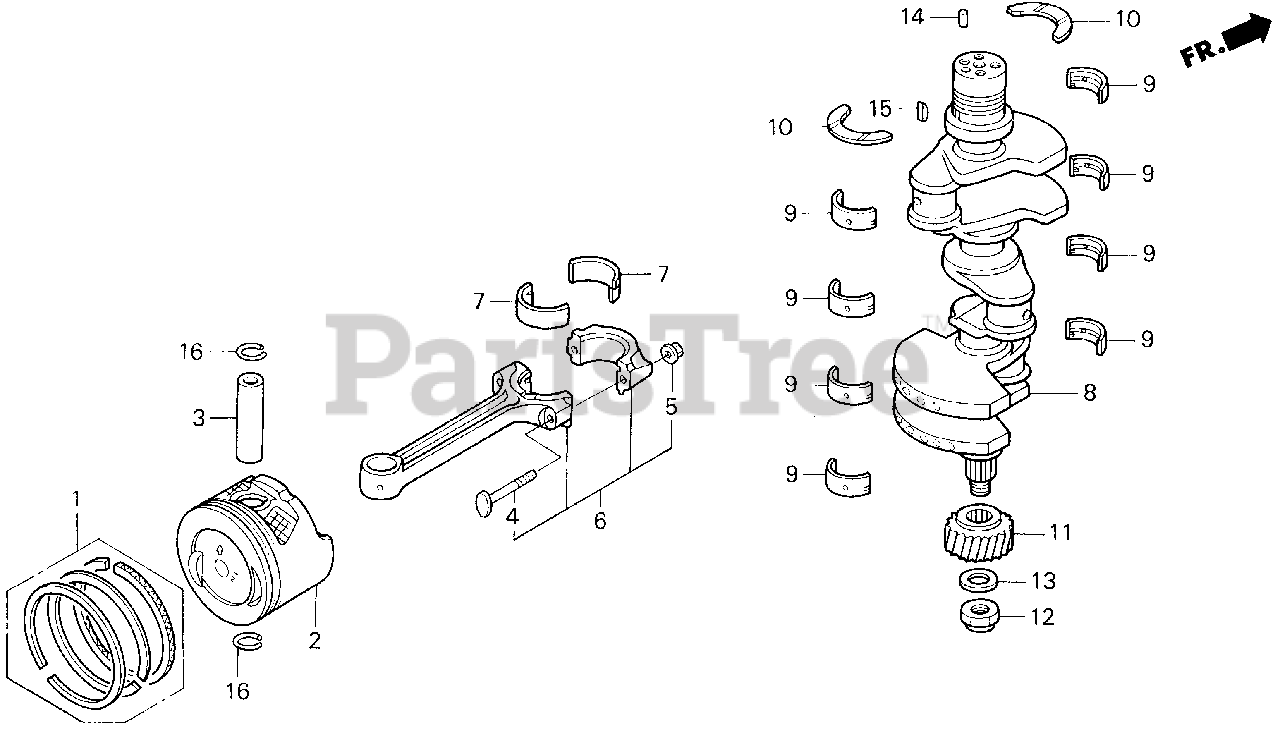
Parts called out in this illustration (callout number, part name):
1	RING SET, PISTON
1	RING SET, PISTON (OS 0.25)
2	PISTON (OS 0.25)
3	PIN, PISTON
4	BOLT, CONNECTING ROD
5	NUT, CONNECTING ROD
6	ROD SET, CONNECTING
7	BEARING A, CONNECTING ROD (BLUE)
7	BEARING B, CONNECTING ROD (BLACK)
7	BEARING C, CONNECTING ROD (BROWN)
7	BEARING D, CONNECTING ROD (GREEN)
7	BEARING E, CONNECTING ROD (YELLOW)
7	BEARING F, CONNECTING ROD (PINK)
7	BEARING G, CONNECTING ROD (RED)
8	CRANKSHAFT
9	BEARING A, MAIN (BLUE) (DAIDO)
9	BEARING B, MAIN (BLACK) (DAIDO)
9	BEARING C, MAIN (BROWN) (DAIDO)
9	BEARING D, MAIN (GREEN) (DAIDO)
9	BEARING E, MAIN (YELLOW) (DAIDO)
9	BEARING F, MAIN (PINK) (DAIDO)
9	BEARING G, MAIN (RED) (DAIDO)
10	WASHER, THRUST
11	GEAR A, PRIMARY DRIVE (26T) (WHITE)
11	GEAR B, PRIMARY DRIVE (26T) (BLUE)
11	GEAR C, PRIMARY DRIVE (26T) (YELLOW)
12	NUT, HEX. (22MM)
13	WASHER (22MM)
14	PIN, DOWEL (6X10)
15	KEY, WOODRUFF (25X14)
16	CLIP, PISTON PIN (18MM)
